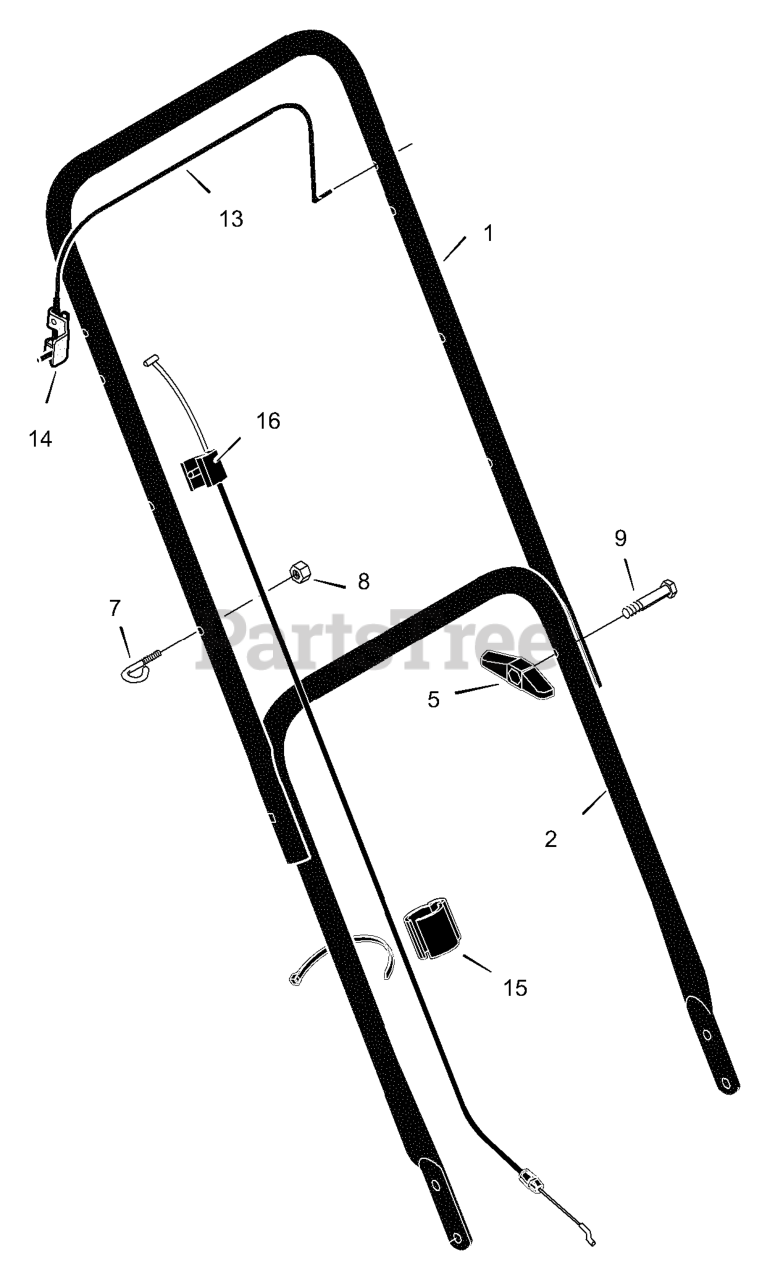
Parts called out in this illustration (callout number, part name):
1	Handle, Upper (Black)
2	Handle, Lower (Black)
5	Knob, Plastic
7	Guide, Rope
8	Locknut
13	Engine Stop Lever
14	Bracket, Stop Lever
15	Fastener, Cable
16	Engine Stop Cable
